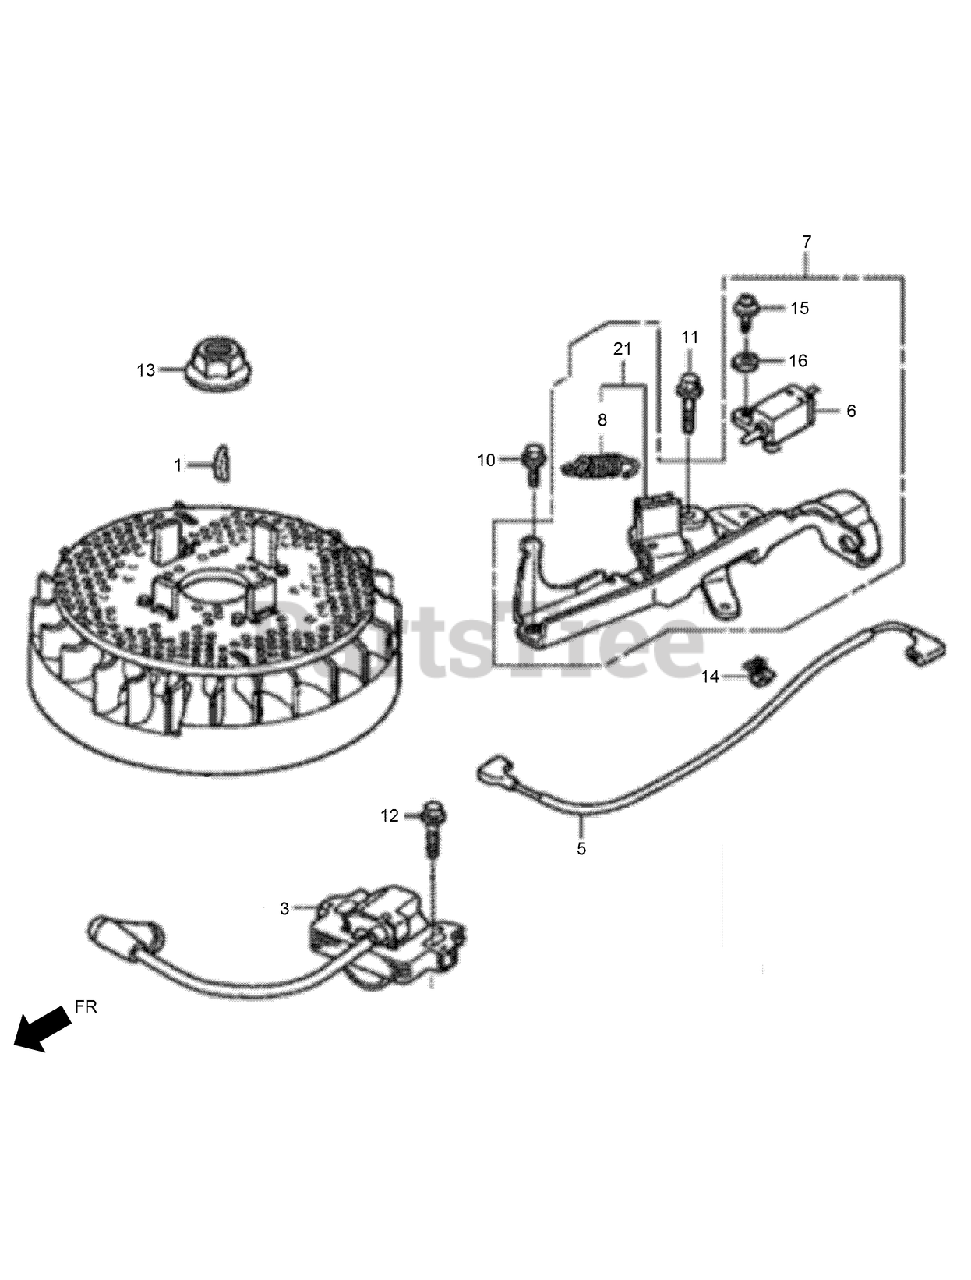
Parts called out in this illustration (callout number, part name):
1	KEY-SPECIAL WOODRUFF-25X18
3	COIL ASM-IGNITION
5	CORD-STOP SWITCH
6	SWITCH ASM-ENGINE STOP
7	BRAKE ASM
8	SPRING-BRAKE LEVER
10	BOLT-FLANGE-6X14
11	BOLT-FLANGE-6X23
12	BOLT-FLANGE-6X23
13	NUT-SPECIAL-14MM
14	CLIP A-CABLE
15	SCREW-WASHER-4X12
16	WASHER-PLAIN-4MM
21	BRAKE SUB ASM
